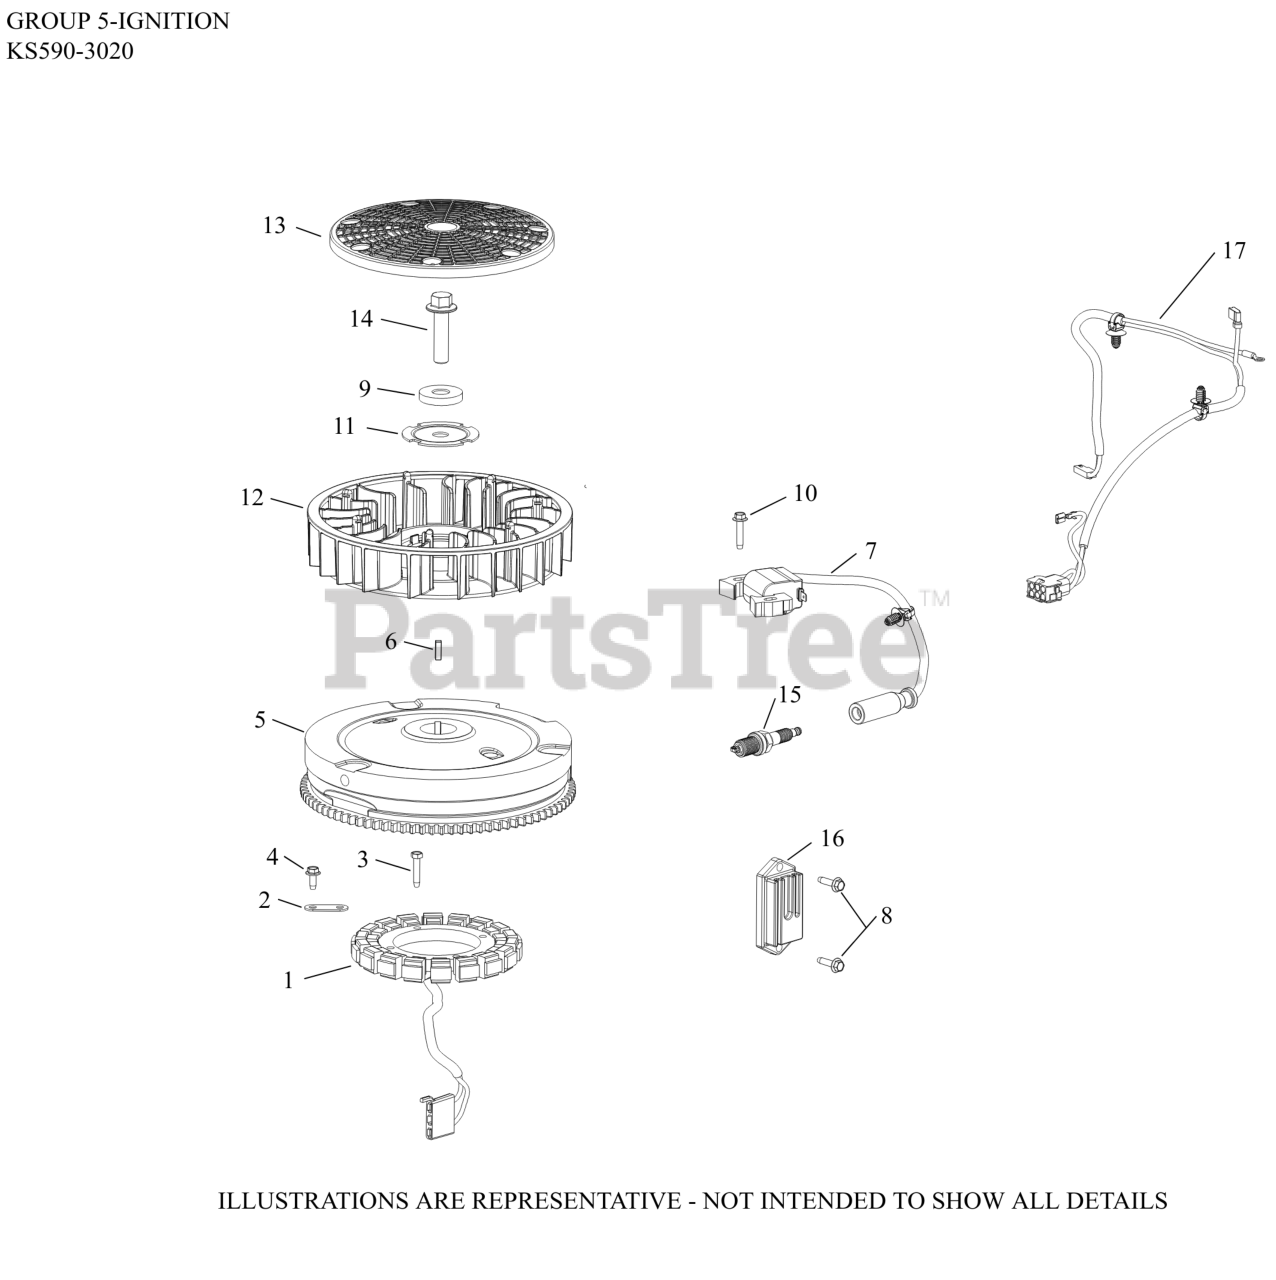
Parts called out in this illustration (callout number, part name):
1	STATOR ASSY, 12A
2	CLIP, STATOR WIRE
3	SCREW, THREAD FORMING
4	SCREW, FLG THD FRM M5X0.8X13
5	FLYWHEEL, ASSY
6	KEY, SQUARE
7	MODULE, INDUCTIVE IGNITION COIL
8	SCREW, THD FRM-USE 25 086 473-S
9	WASHER, FLAT
10	SCREW, THREAD FORMING
11	PLATE, FAN MOUNTING
13	SCREEN, GRASS
14	SCREW, HEX FLANGE
15	PLUG SPARK 12MM RFI
16	REGULATOR/RECTIFIER 12/15A HALF-WAVE STD
17	HARNESS, WIRING NON-OSU, NON MTD
